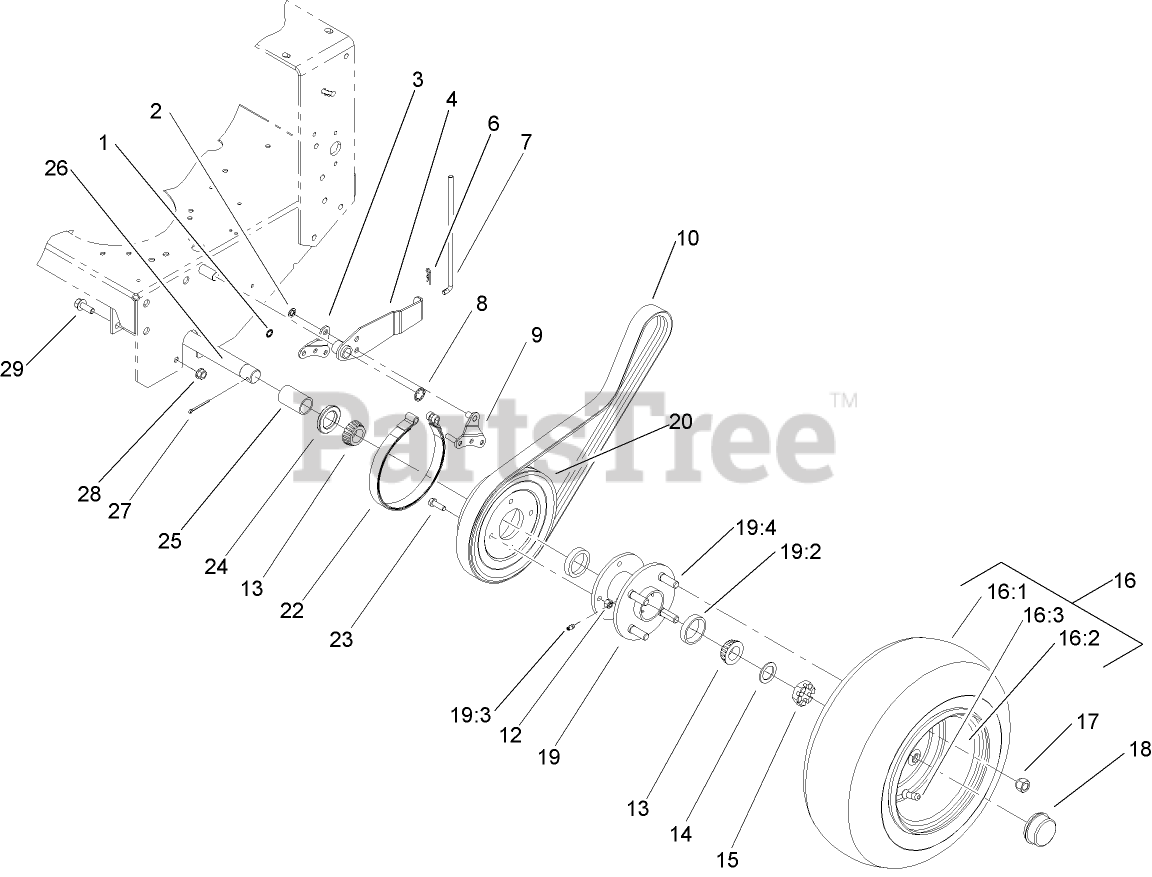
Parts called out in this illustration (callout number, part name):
1	RING-RETAINING
2	RING-RETAINING, EXTERNAL
3	PLATE-LINK, BRAKE
4	BRAKE ARM ASM
6	PIN-COTTER
7	ROD-BRAKE
8	RING-RETAINING
9	BRAKE LINK ASM
10	V-BELT
12	NUT-LOCK, NI
13	BEARING-CONE, TAPERED
14	WASHER-SPACER
15	NUT-SHH
16	WHEEL AND TIRE ASM
16:3	STEM-VALVE
17	NUT-LUG
18	CAP-DUST
19	HUB/WHEEL ASM
19:2	BEARING-CUP, TAPERED
19:3	FITTING-GREASE
19:4	STUD-WHEEL
20	PULLEY-WHEEL
22	BAND-BRAKE
23	SCREW-HH
24	SEAL-GREASE
25	SPACER-WHEEL
26	AXLE ASM
27	PIN-COTTER
28	NUT-HF
29	SCREW-HHF
